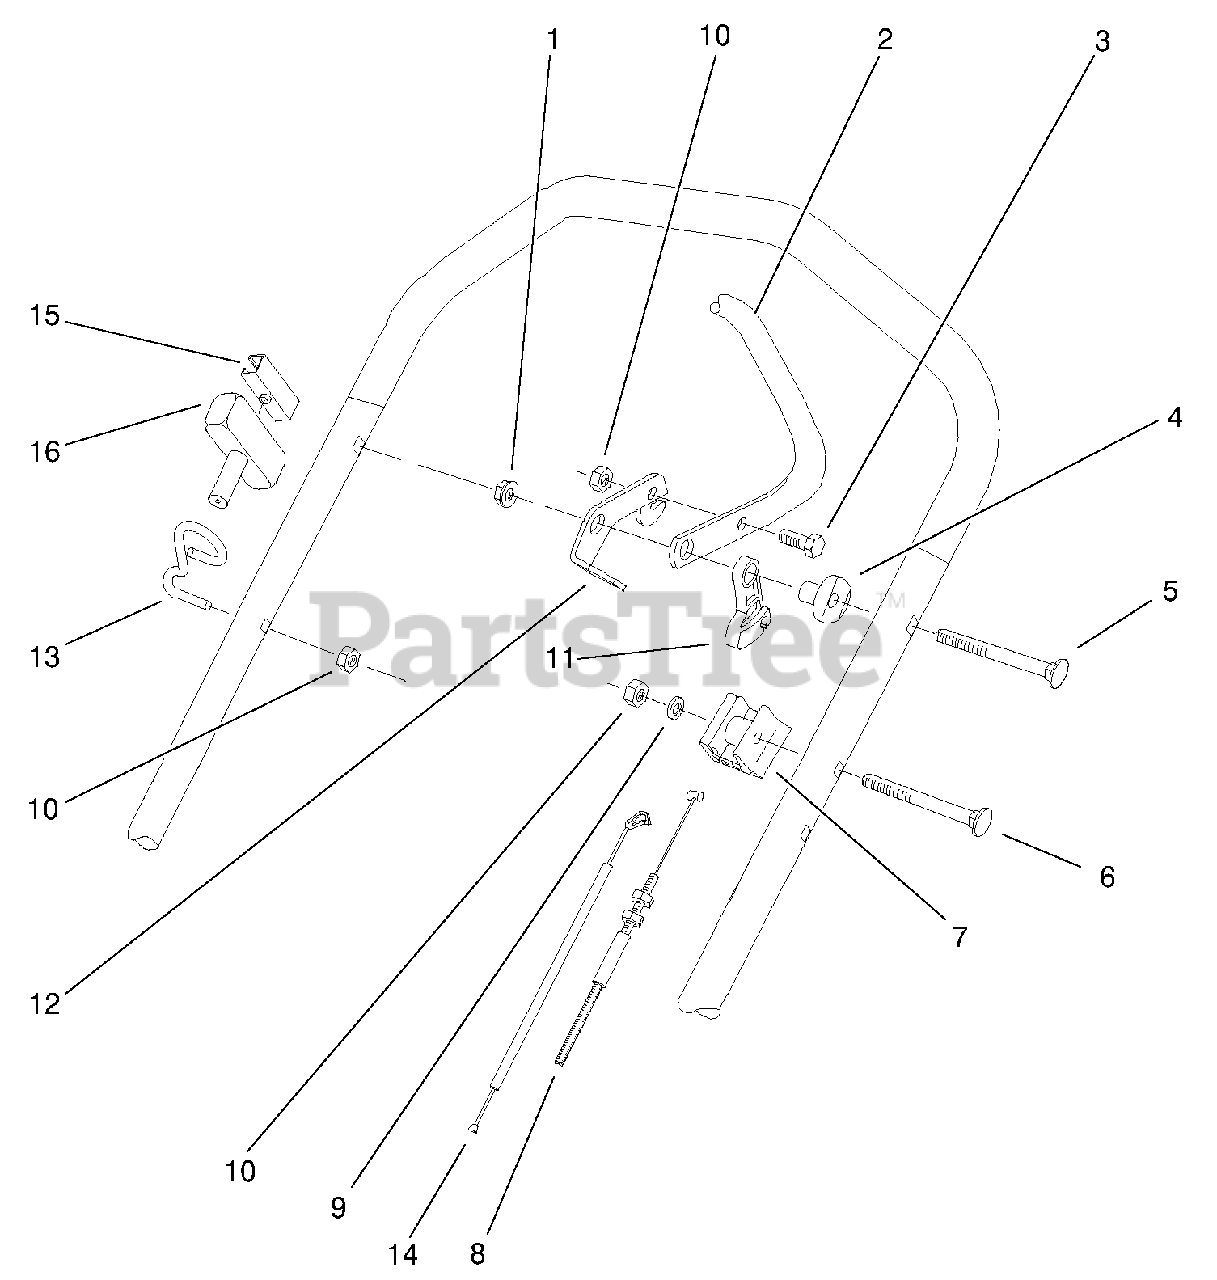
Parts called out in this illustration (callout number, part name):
1	Nut-Lock NI
2	Bar-Control
3	Screw-HH
4	Spacer-Support
5	Handle Screw
6	Screw-Handle
7	Cable Support
8	Cable-Traction
9	Washer-Flat
10	Nut-Lock, NI
11	Lever-Traction
12	Lever-Control
13	Guide-Rope
14	Cable-Brake
15	Starter-Clip
16	Handle-start
